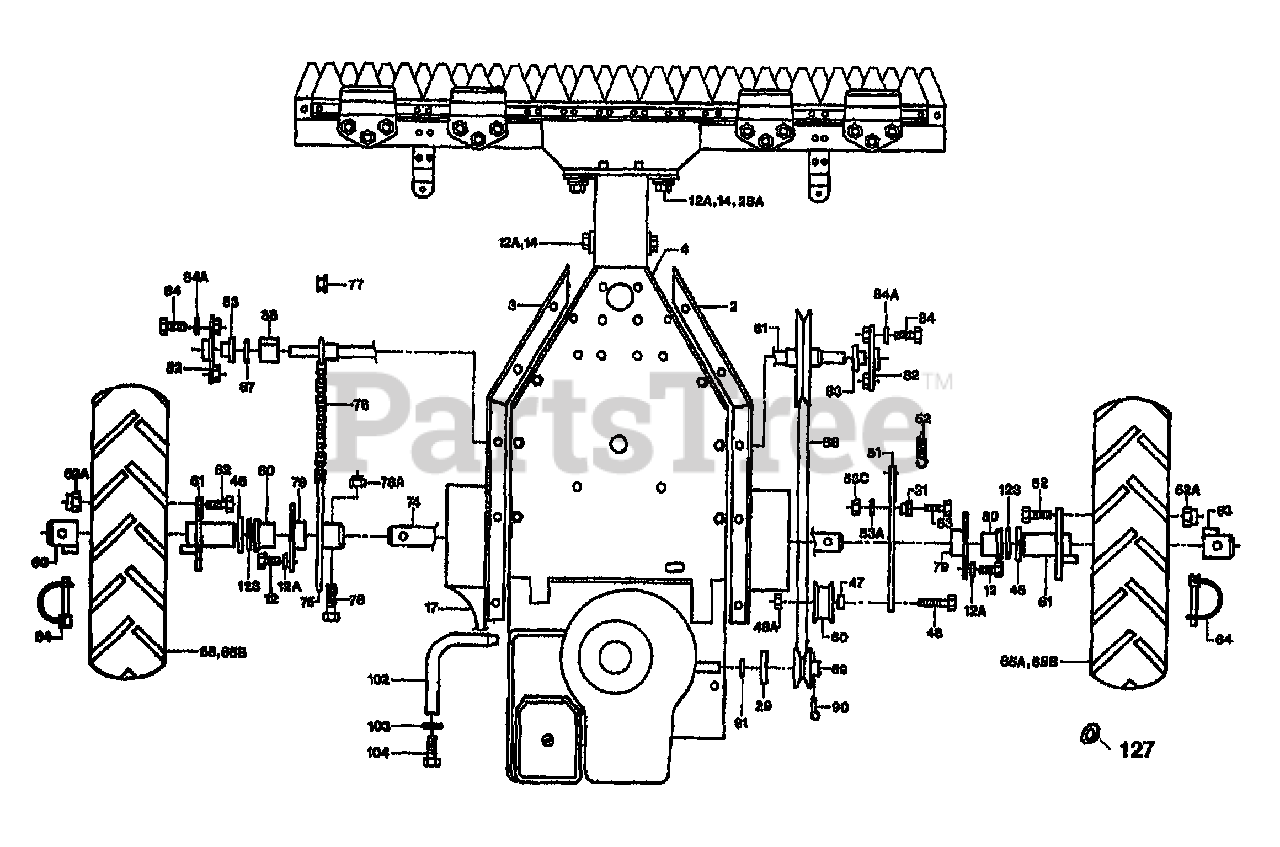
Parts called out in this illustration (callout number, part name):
2	Frame Plate-Right
3	Frame Plate-Left
4	Frame Plate-Bottom
12	Screw-HHM8 x 12
12A	Washer
14	Screw-HHM8 x 16 Grade 10.9
17	Grass Shield-Wheel-LH
28A	Washer
29	Belt Guide
31	Clutch Plate Bushing
45	Snap Ring
47	Spacer-Pulley
48	Screw-HHM12 x 40
48A	Nylon Nut
51	Clutch Plate
52	Spring-Clutch Plate
53	Screw-HHM10 x 35
53C	Nut-Nylon-HM10
61	Wheel Hub
62A	Lug Nut
63	Three-way Hub Lock
64	Retaining Clip
65	Wheel and Tire LH
65A	Wheel and Tire RH
74	Wheel-Axle
75	Sprocket-Wheel Axle
76	Chain & Master Link
77	Master Link
78	Screw-HHM8 x 45
78A	Nylon Nut
79	Flange w/Bushing-Axle
80	Bushing-Wheel Axle
81	Jack Shaft Kit
82	Flange-Bearing Shaft
83	Bushing-Shaft
84	Screw-HHM6 x 12
84A	Washer
85	Spacer-Flange
88	V-Belt-Wheel Drive
89	Pulley-Eng. Drive
90	Cotter Pin
91	Washer-Felt
102	Tube-Oil Drain
103	Washer-Copper
104	Screw-HHM12 x 18
123	Washer-Wheel
127	Wheel Spacer
